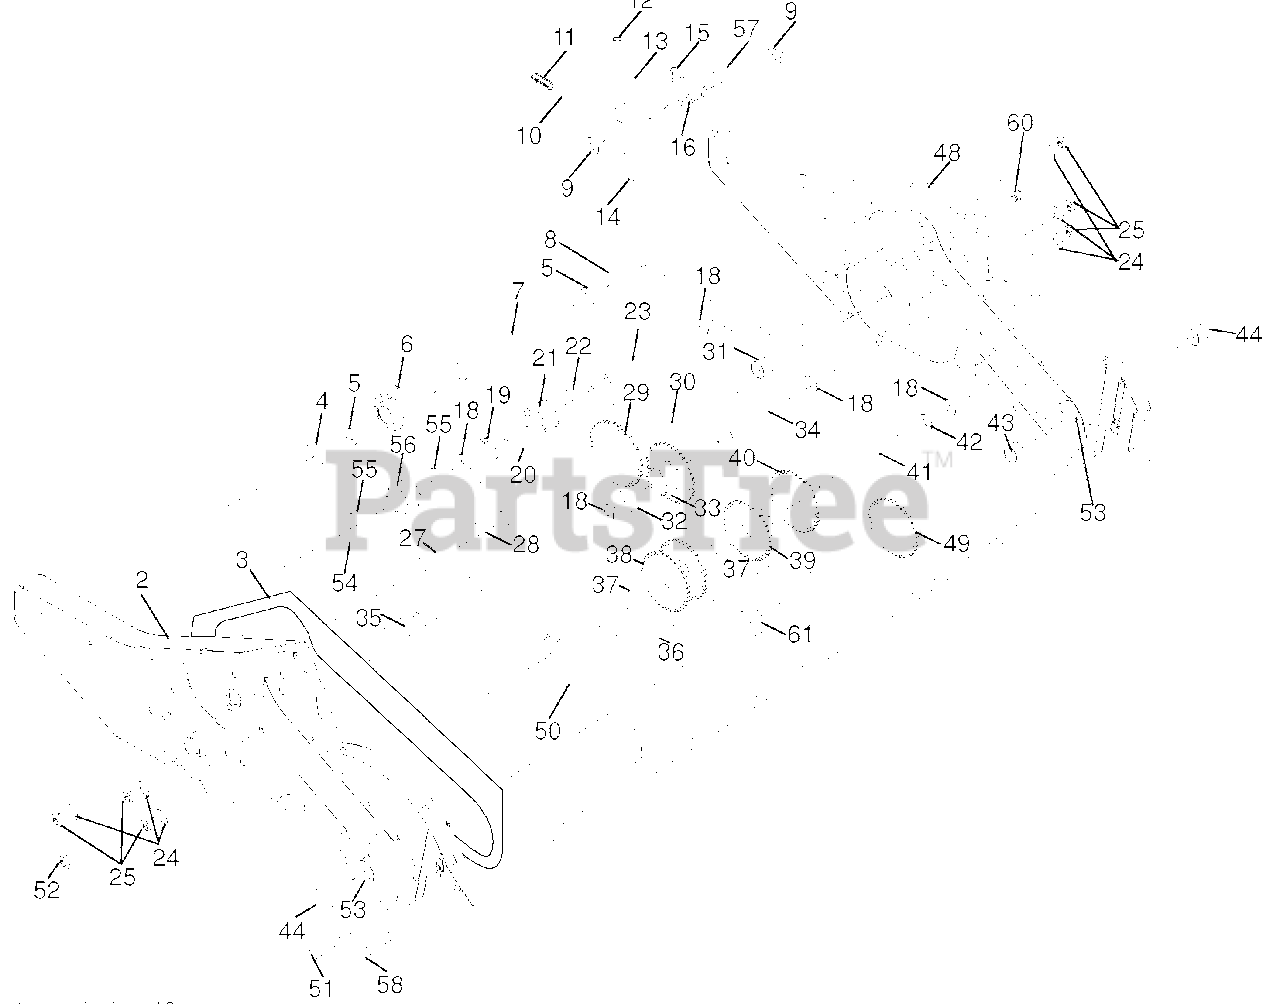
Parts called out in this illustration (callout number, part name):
1	Trans mis sion Assembly
2	Gearcase, L.H. w/Bearing
3	Gasket, Gearcase
4	Bearing, Needle
5	Washer, Thrust 5/8 x 1.10 x 1/32
6	Pinion, Input
7	Shaft, In put
8	Bearing, Needle
9	Washer, Seal
10	Ball, Steel
11	Spring, Shift, Fork
13	Arm, Shift
14	Fork, Shift
15	Ring, Klip
16	Shaft, Shift
19	Ring, Klip
20	Gear, As sem bly, Reverse Idler
21	Gear, Re verse Idler
22	Bearing, Needle
23	Shaft, Re verse Idler
24	Washer, Lock 7/16
25	Nut, Hex 7/16-20
27	Bearing, Shaft, Ground Drive L.H.
28	Spacer 0.765 x 1.125 x 1.23
29	Chain #35-50 Pitch
30	Ground Shaft Assembly
31	Bearing, Shaft, Ground Drive R.H.
32	Spacer 0.70 x 1.00 x 1.150
33	Sprocket and Gear Assembly
34	Shaft, Re duc tion (2nd)
35	Screw, Whiz, Lock 5/16-18 x 3-1/2
36	Sprocket Assembly w/Bearing
37	Bearing, Needle
38	Sprocket, Tine
39	Gear, Clus ter, Red 1st & 2nd
40	Gear, Re verse
41	Shaft, Re duc tion (1st)
42	Washer, Thrust
43	Spacer 1.01 x 1.75 x 0.760
44	Seal Asm. OIl
48	Gearcase, R.H. w/Bearing
49	Shaft, Tine
50	Chain, Roller #50-50 Pitch
51	Screw 1/4-20 x 1/2
52	Nut, Hex 5/16-18
53	Bearing Kit, Tine Shaft
54	Gear, DRT Idler w/Bearing
55	Bearing, Needle
56	Gear, DRT Idler
57	Spacer, Split .52 x .64 x 1.04
58	Screw 1/4-20 x .875
60	Fitting Grease
61	Spacer 1.015 x 1.50 x .656
